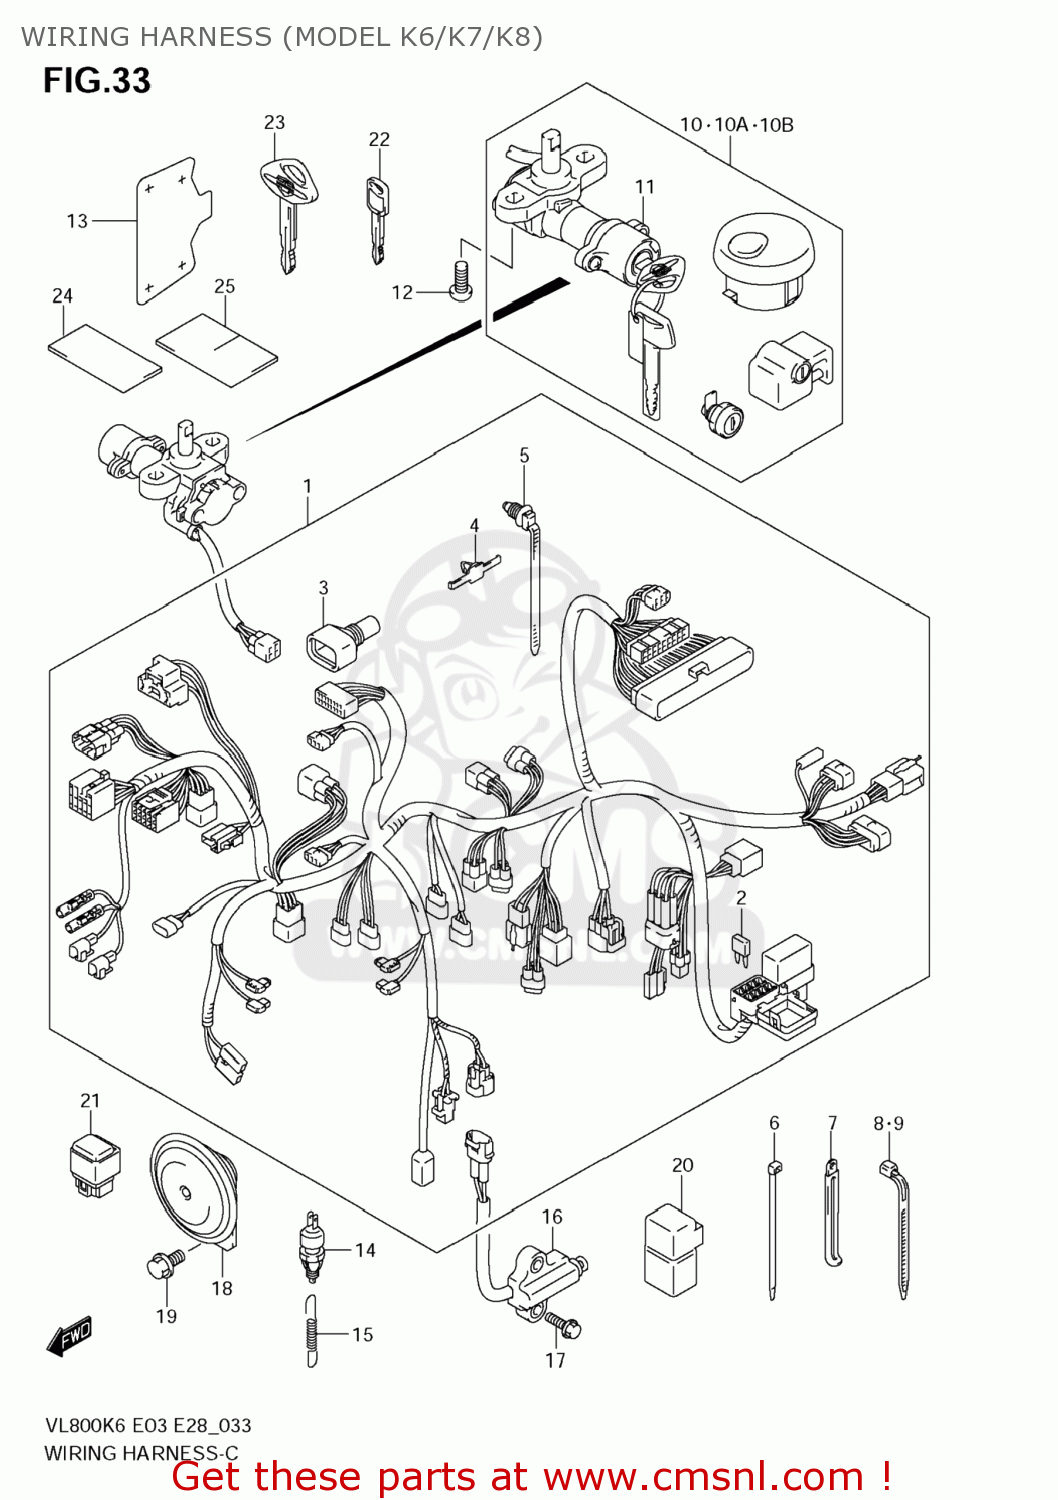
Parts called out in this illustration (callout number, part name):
1	HARNESS,WIRING
2	FUSE(10A)
3	COVER,SPEEDOMETER COUPLER
4	CLAMP
5	CLAMP(L:154)
6	CLAMP(L:145)
7	CLAMP(L:80)
8	CLAMP(L:165)
9	CLAMP(L:190)
10	LOCK SET
10A	LOCK SET
10B	LOCK SET
11	LOCK ASSY,STEERING
12	BOLT(8X20)
13	PROTECTOR,IGNITION SWITCH
14	SWITCH ASSY,STOP LAMP
15	SPRING
16	SWITCH ASSY,SIDE STAND
17	BOLT(6X20)
18	HORN ASSY
19	BOLT
20	RELAY ASSY
21	RELAY ASSY
22	KEY,BLANK
23	KEY,BLANK(BOULEVARD)
24	TAPE,WIRING HARNESS(28X50X0.13
25	PROTECTOR,HARNESS(30X50X3)
